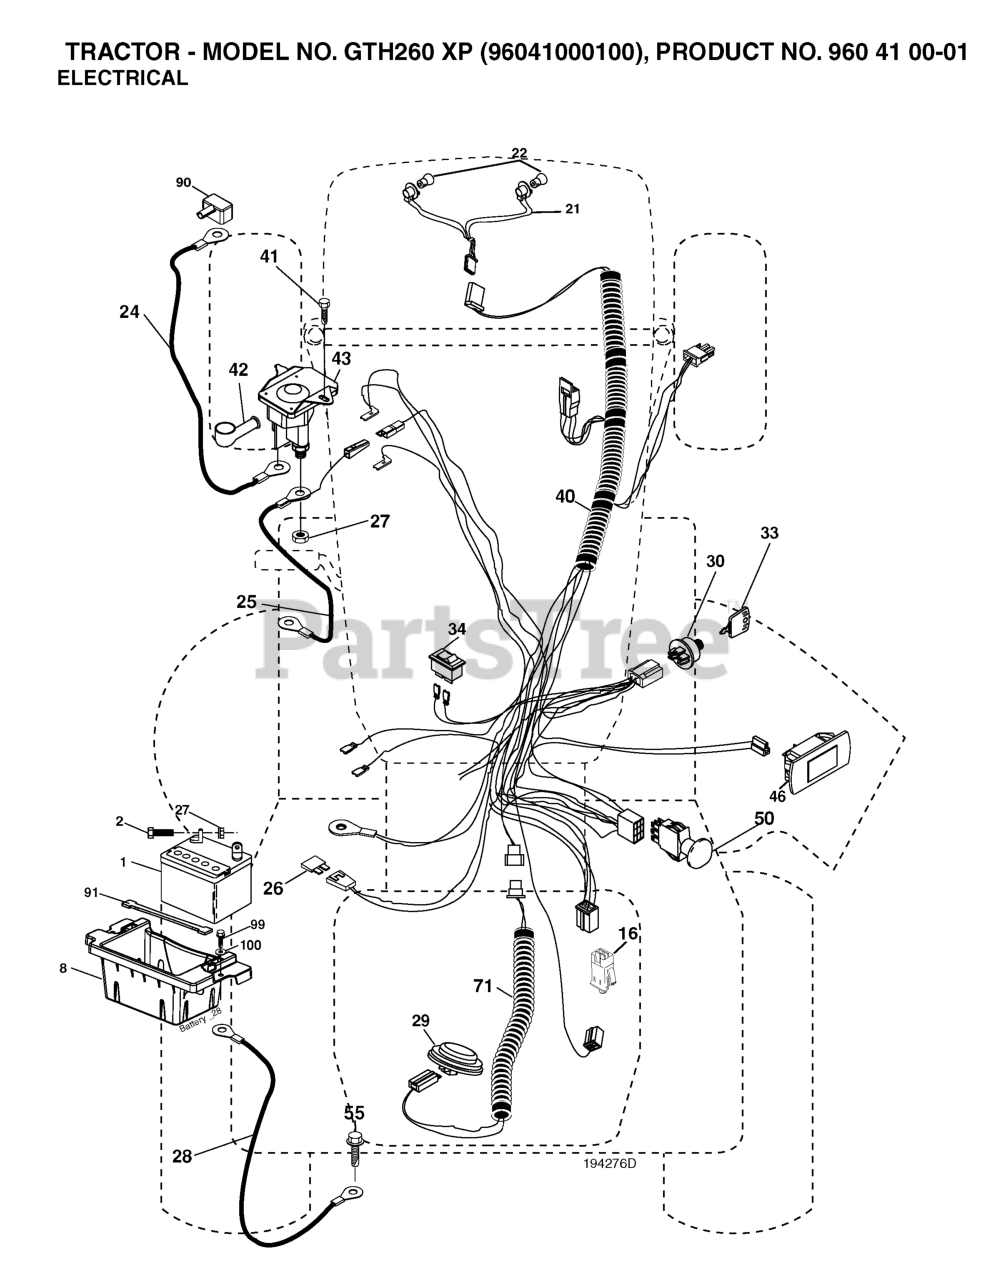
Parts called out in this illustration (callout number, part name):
1	BATTERY 12V .35 AMP
2	BOLT.HEX.1/4.X.3/4.DICHROMATE
8	BOX.BATTERY.MOUNT.FRONT.LT
16	SWITCH INTERLOOK PUSH-IN
21	HARNESS ASSY LIGHT
26	FUSE 20AMP
28	CABLE GROUND 6 GA 21" 90T BLK
29	SWITCH.SEAT.DELTA.OPC.
30	SWITCH.IGN.DELTA.W.LGH.ROS
33	KEY MLD GEN DELTA
40	HARNESS-CHASSIS SUB
42	COVER.TERMINAL.RED
46	GAUGE.SERVICEMINDER.HR
50	RP.PTO.SWITCH.8 TERMINAL.BLACK
55	Screw 5/16-18 x 1/2 Hex, Self Tapping 5/16-18 x 1/2
71	HARNESS.IGN.DASH.HUQ/P
90	COVER TERMINAL
91	STRAP.BATTERY.MOUNT.FRONT(2 2)
99	SCREW HEXWSHR 1/4-20X3/4
